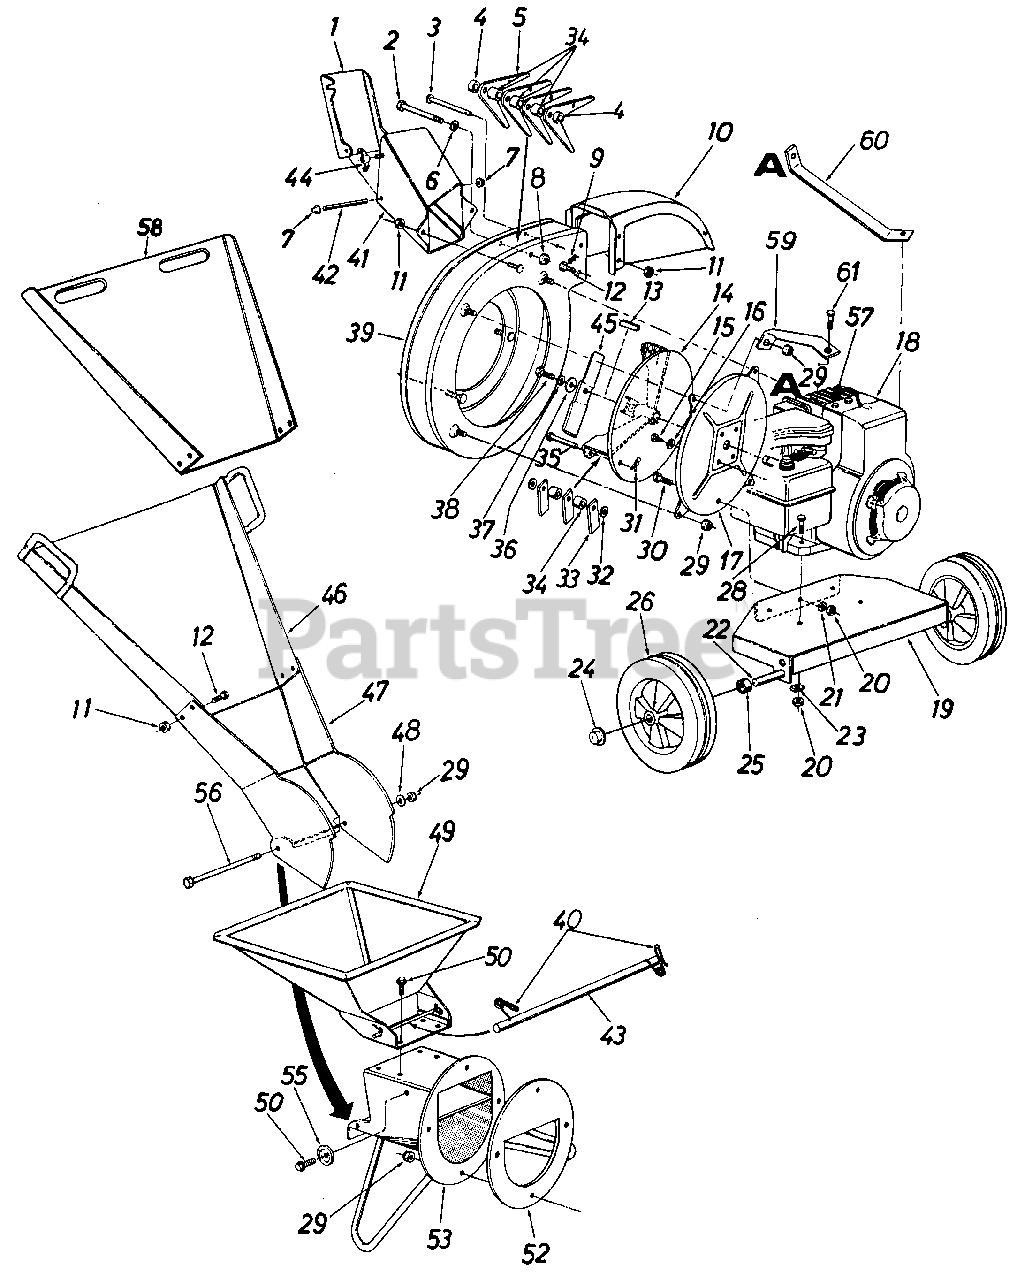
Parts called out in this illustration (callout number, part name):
2	SCREW-HEX 1/2-20 X 4.50
3	PIN-CLEVIS-5/16 X3 5/8
5	CUTTING FINGER
6	WASHER-LOCK-1/2
8	NUT-HEX JAM 1/2-20
9	PIN-COTTER-3/32 DIA X .75
10	DEFLECTOR-CHUTE
11	NUT-HEX CENTER L-1/4-20
12	SCREW-HEX 1/4-20 X .50
13	PIN-COTTER-1/8 DIA X 1.00
14	IMPELLER ASSY-COMP
15	SCREW-HEX 5/16-24 X .75
16	WASHER-LOCK-5/16
17	PLATE-MTG
19	PLATE-ENGINE MTG
20	NUT-5/16-24
21	WASHER-LOCK-5/16
23	WASHER-SPEC L 5/16 X .88 OD
26	WHEEL ASSY W/TIRE
28	SCREW-5/16-24 X 1.5
29	NUT-HEX INS L-5/16-18
30	SCREW-HEX 5/16-24 X .62
31	PIN-COTTER-1/8 DIA X 1
32	WASHER-FL-.531 ID X .93 OD X .090
33	FLAIL
34	SPACER-FLAIL
35	PIN-CLEVIS-1/2 X 3
36	WASHER-FL
37	WASHER-HDL 3/8
38	SCREW-HEX 3/8-24 X 2.00
41	EXTENSION ASSY-GUARD
42	PIN-HINGE
43	BAR-RELEASE
44	NUT-INS WING L-1/4-20
47	RAMP-SECTION-LWR LEAF
48	WASHER-FL-.344 X .62
49	HOPPER ASSY
50	SCREW-HEX WASH SF TAPP
52	PLATE-BACK-UP
53	GUIDE ASSY-INLET
55	WASHER-STOP
56	SCREW-HEX 5/16-18 X 8.25
57	INSULATOR-SPARK PLUG
60	BRACE-SUPPORT-LH
